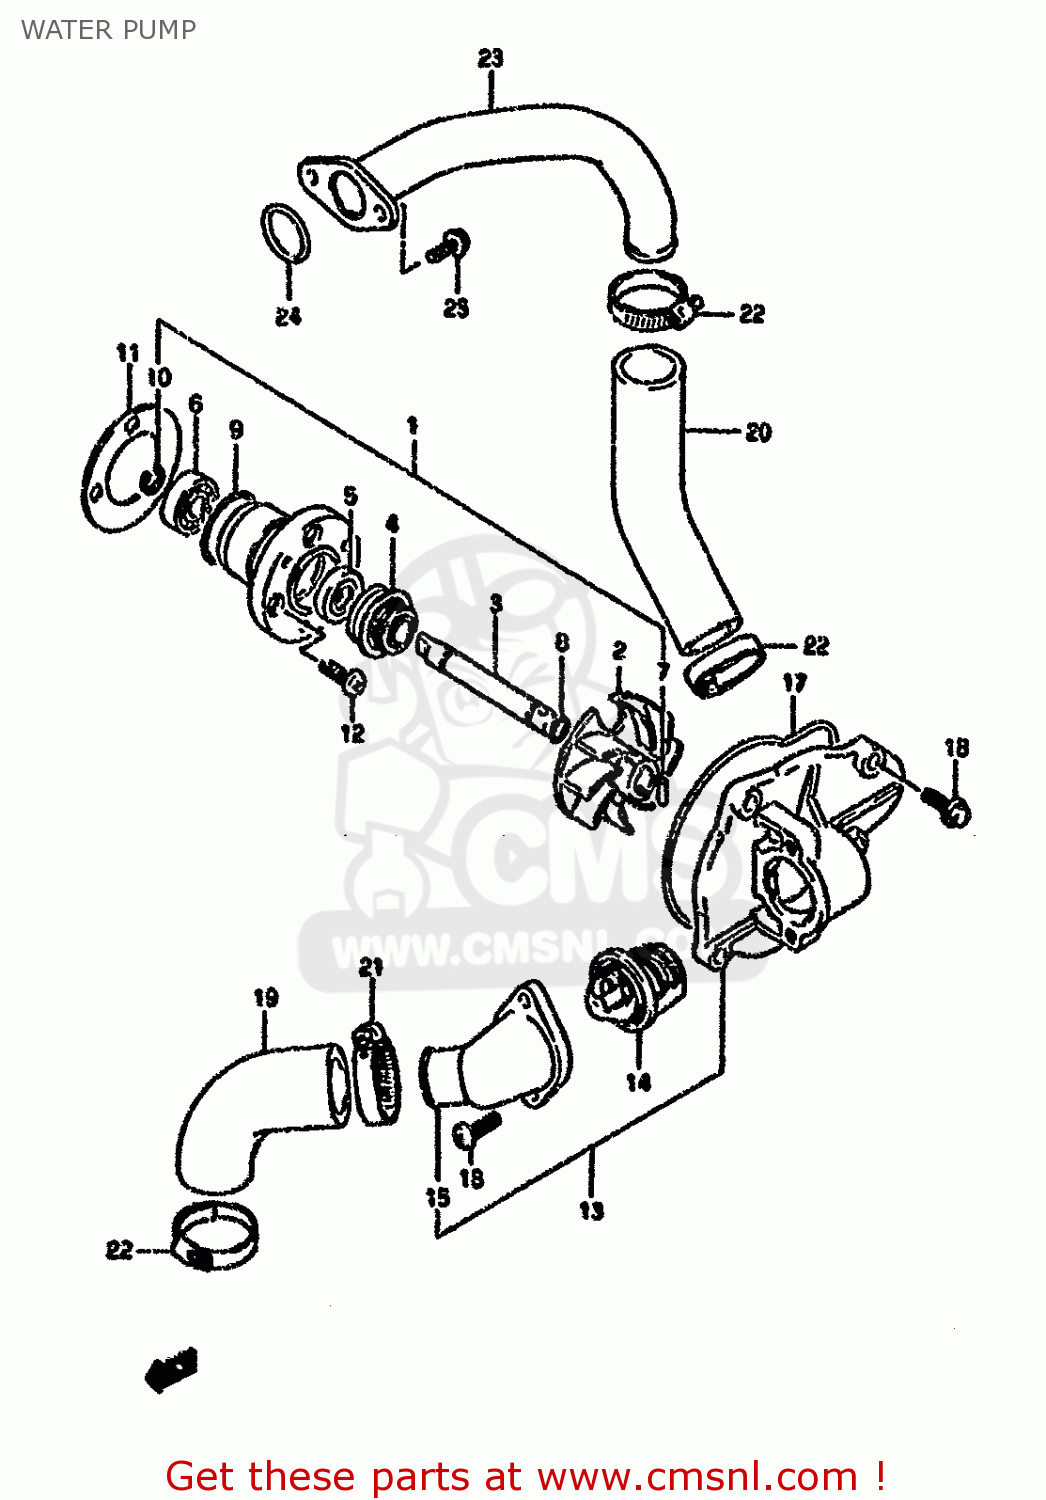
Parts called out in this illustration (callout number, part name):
1	PUMP ASSEMBLY,WATER
2	IMPELLER
3	SHAFT
4	SEAL,MECHANICAL
5	OILSEAL
6	BEARING,10X26X8
7	PIN
8	O RING
9	O RING
10	E RING
11	GASKET,WATER PUMP (NAS)
12	SCREW
13	CAP ASSY,WATER PUMP
14	THERMOSTAT,WATER
15	CONNECTOR
16	SCREW
17	O RING,WATER PUMP CAP
18	BOLT
19	HOSE,WATER PUMP IN
20	HOSE,WATER
21	CLAMP
22	CLAMP
23	PIPE,CYLINDER INLET
24	O RING(D:2.3,ID:24.4)
25	BOLT
